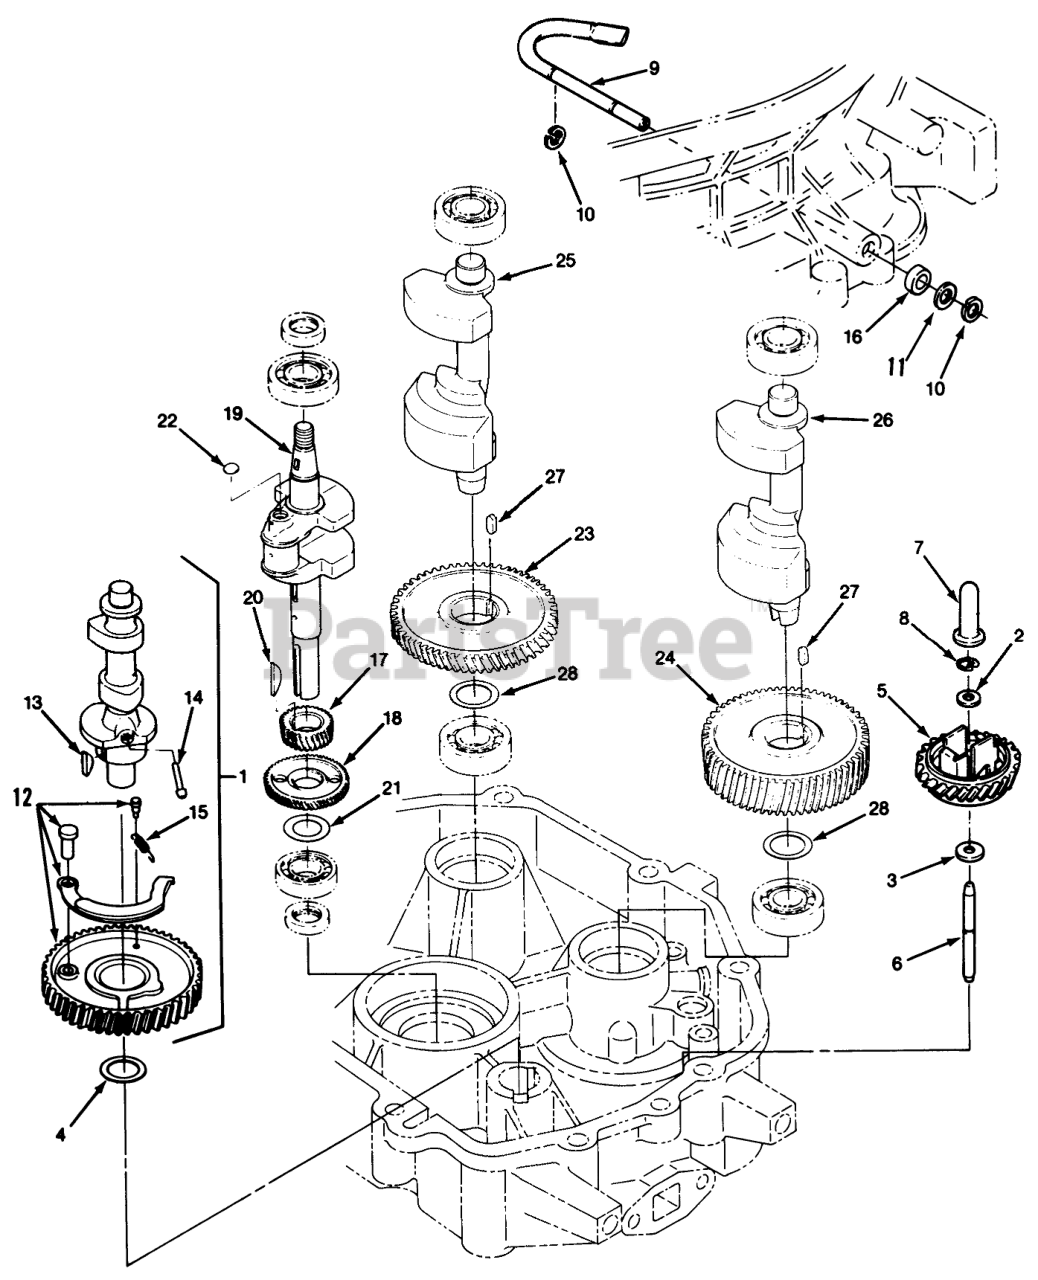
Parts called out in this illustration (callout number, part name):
1	Camshaft Assembly (Incl. Ref. #12-15)
2	WASHER-1.6MM THK
3	WASHER-1MM THK
4	SHIM-CAMSHFT 0.5MM
5	GEAR-GOVERNOR
6	SHAFT-GOVERNOR
7	Sleeve
8	STOP-GOVERNOR
9	SHAFT-GOVERNOR LEVER
10	CLIP-RETAINER
11	Nut-M8
12	CAMGEAR ASS'Y
13	KEY-CAMGEAR
14	PIN-DECOMPRESSION
15	SPRING-DECOMPRESSION
16	SEAL-GVR SHAFT LEVER
17	GEAR-CRANKSHAFT
18	GEAR-BALANCER
19	Crankshaft
20	KEY-CRANKSHAFT GEAR
21	SHIM-CRANKSHFT 0.2MM
22	PLUG-EXPANSION
23	GEAR-BALANCER
24	GEAR-BALANCER
25	SHAFT-BALANCER
26	SHAFT-BALANCER
27	KEY-BALANCER GEAR
28	SHIM-BAL SHAFT 0.5MM
